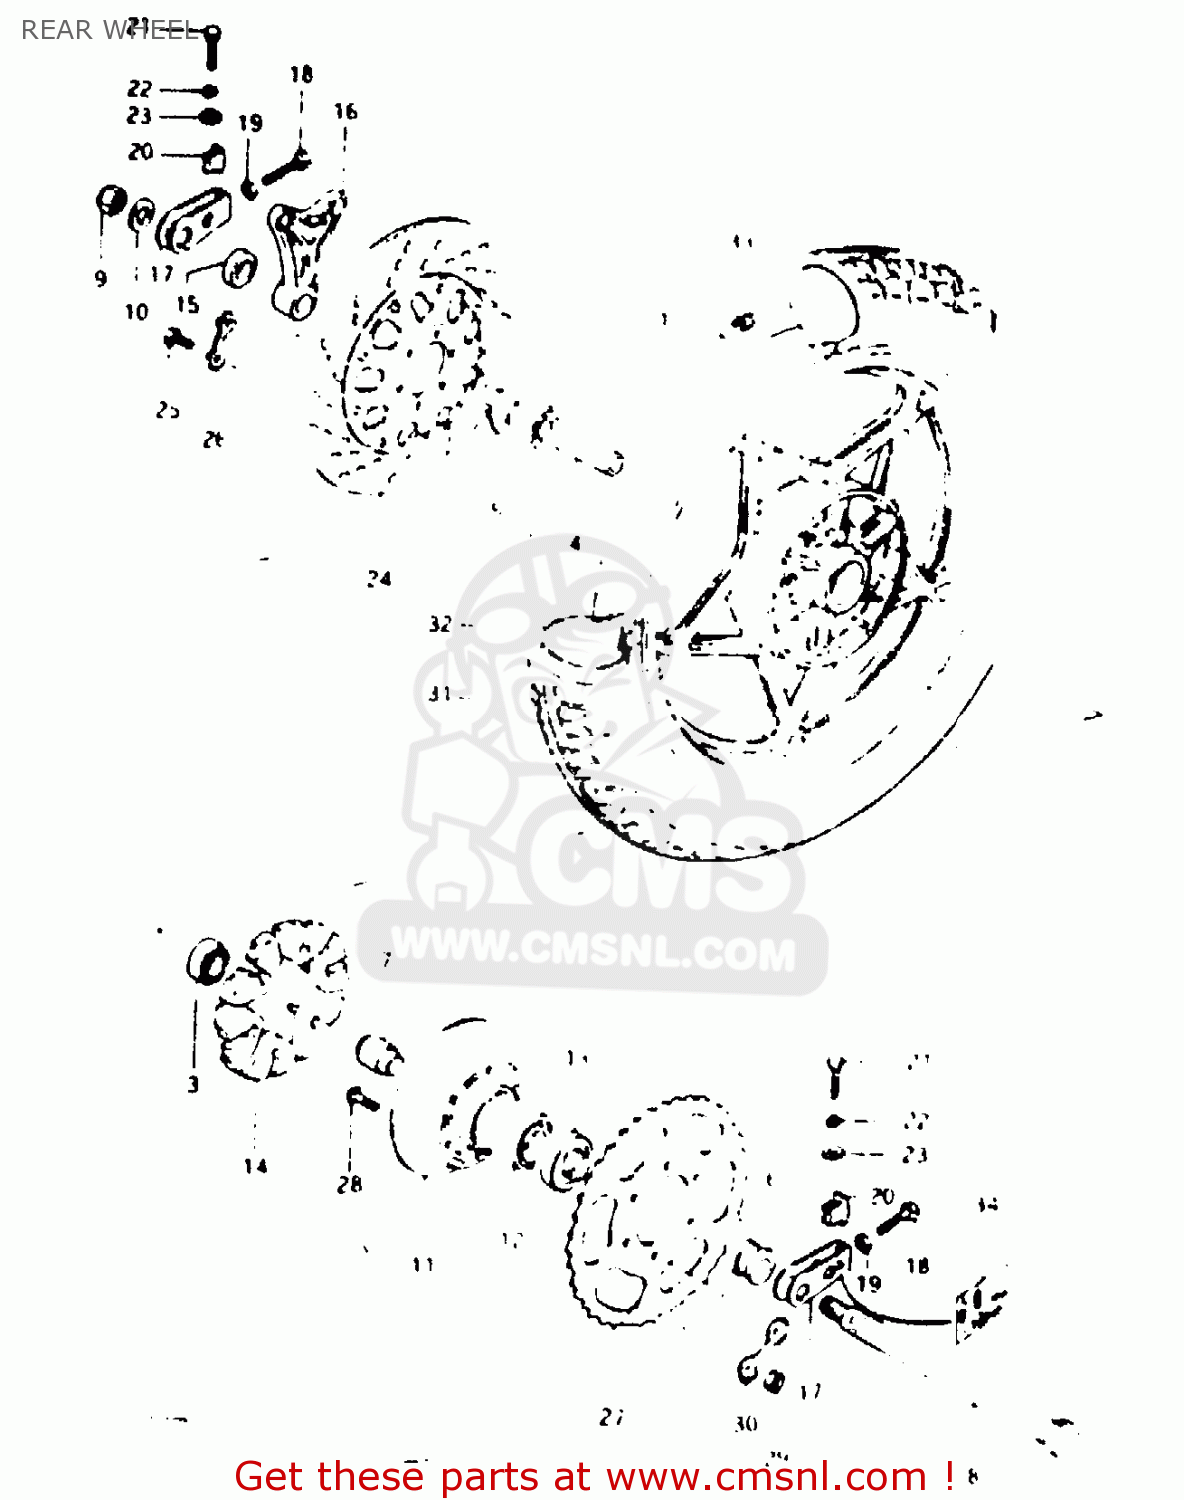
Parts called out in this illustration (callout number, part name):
1	WHEEL, REAR (MT2.50*17)
2	BEARING WHEEL REAR(20X47X14)
3	BEARING, LH
4	SPACER(20.5X28X88)
5	SPACER,REAR AXLE
6	SPACER(20X33X28.3)
7	SPACER,REAR HUB BEARING
8	AXLE,REAR
9	NUT
10	WASHER(19X34X4)
11	DRUM,REAR SPROCKET MOUNT
12	BEARING
13	SEAL,OIL(33X62X7)
14	ABSORBER,REAR HUB SHOCK
15	SPACER(20X38X12)
16	BRACKET,RR,CALIPER
17	ADJUSTER,CHAIN
18	BOLT
19	NUT
20	SUPPORTER,CHAIN ADJUST
21	BOLT
22	LOCK WASHER
23	WASHER
24	DISC,RR BRAKE
25	BOLT(8X30)
26	WASHER
27	SPROCKET,REAR
28	BOLT
29	NUT
30	WASHER
31	TIRE 4.50V17
32	TUBE ASSEMBLY,WHEEL,INNER
33	BALANCER,WHEEL
34	LABEL,CHAIN WEAR INDICATOR
